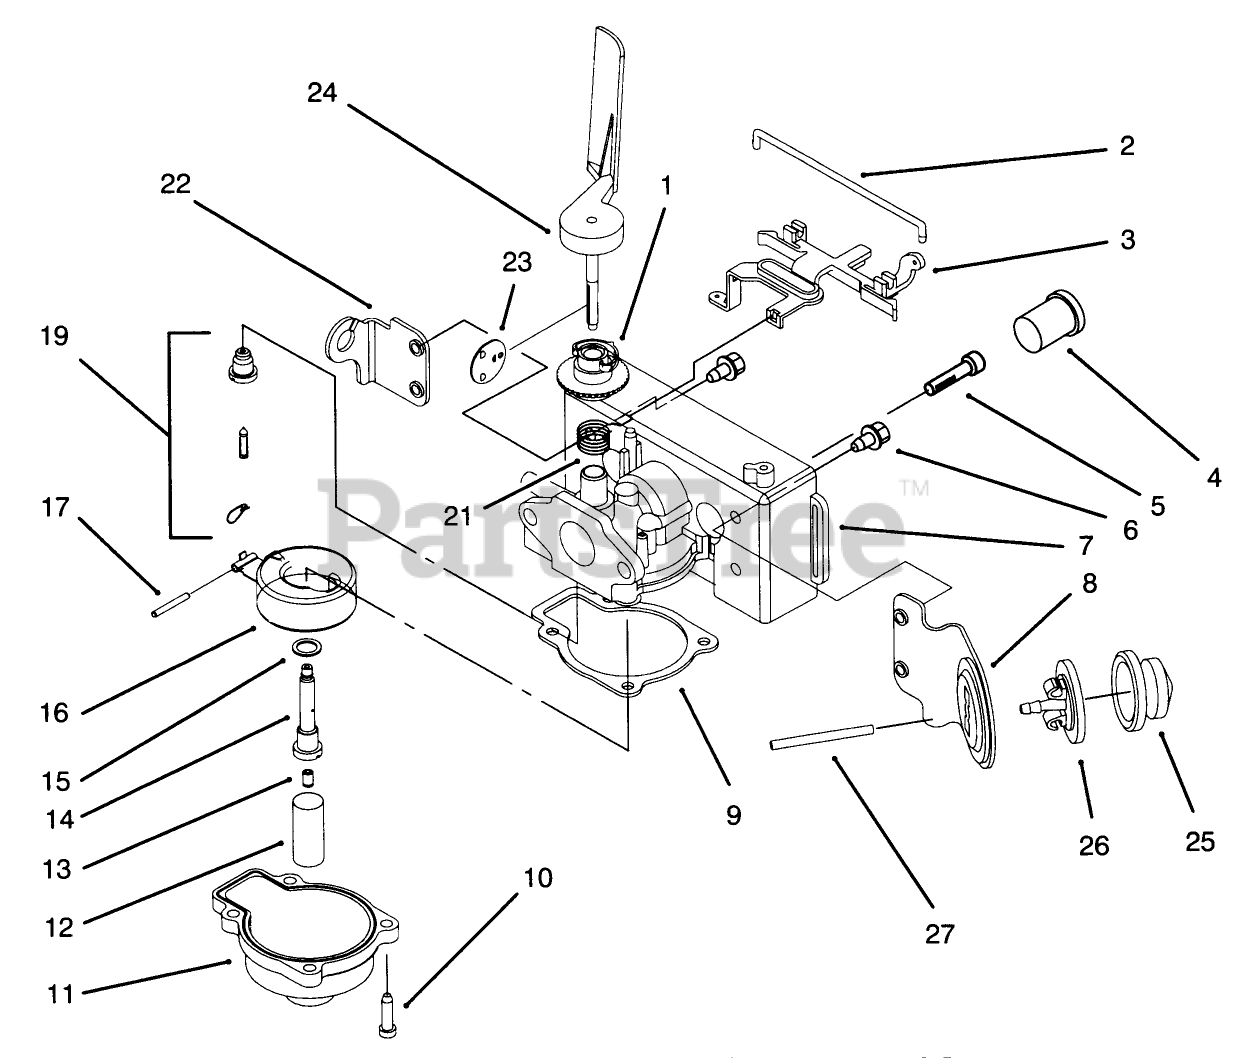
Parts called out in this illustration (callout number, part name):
1	COLLAR-ADJUST, AIRVANE
2	RETAINER
3	LEVER-ADJ. VF
8	BRKT-PRIMER F
10	SCREW-HH
11	CHAMBER-FLOAT
12	FILTER-FUEL VS
13	JET-MAIN VF
17	PIN-STRAIGHT
19	VALVE / SEAT-FLOAT
21	SPRING-GOV V
23	DISC-THRO. V
25	BULB-PRIMER
26	BODY-PRIMER
